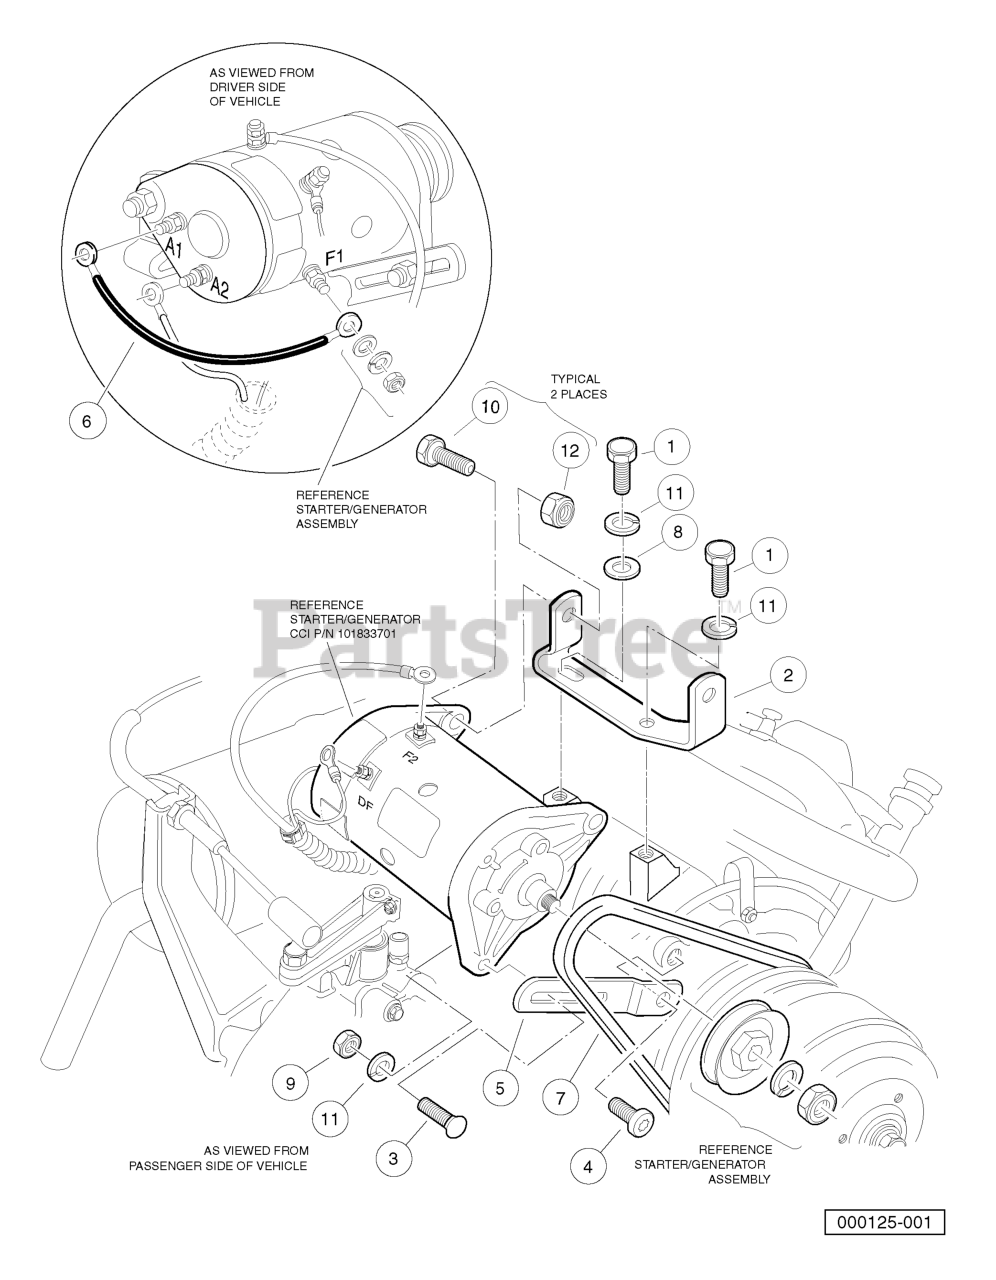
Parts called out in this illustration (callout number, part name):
2	BRACKET, FE350 S/G MOUNTING
3	BOLT, 5/16-18 RD HD SQ NECK
4	SCREW, M8-1.25 X 18MM TORX
5	BRACKET, S/G-ADJUSTABLE
6	WIRE ASSY, #6 GREEN
7	BELT, STARTER-GENERATOR
8	WASHER, 5/16 TYPE A FLAT
9	NUT, 5/16-18 HEX
11	LOCKWASHER, 5/16 SPLIT
12	LOCKNUT, 3/8-16 HEX
